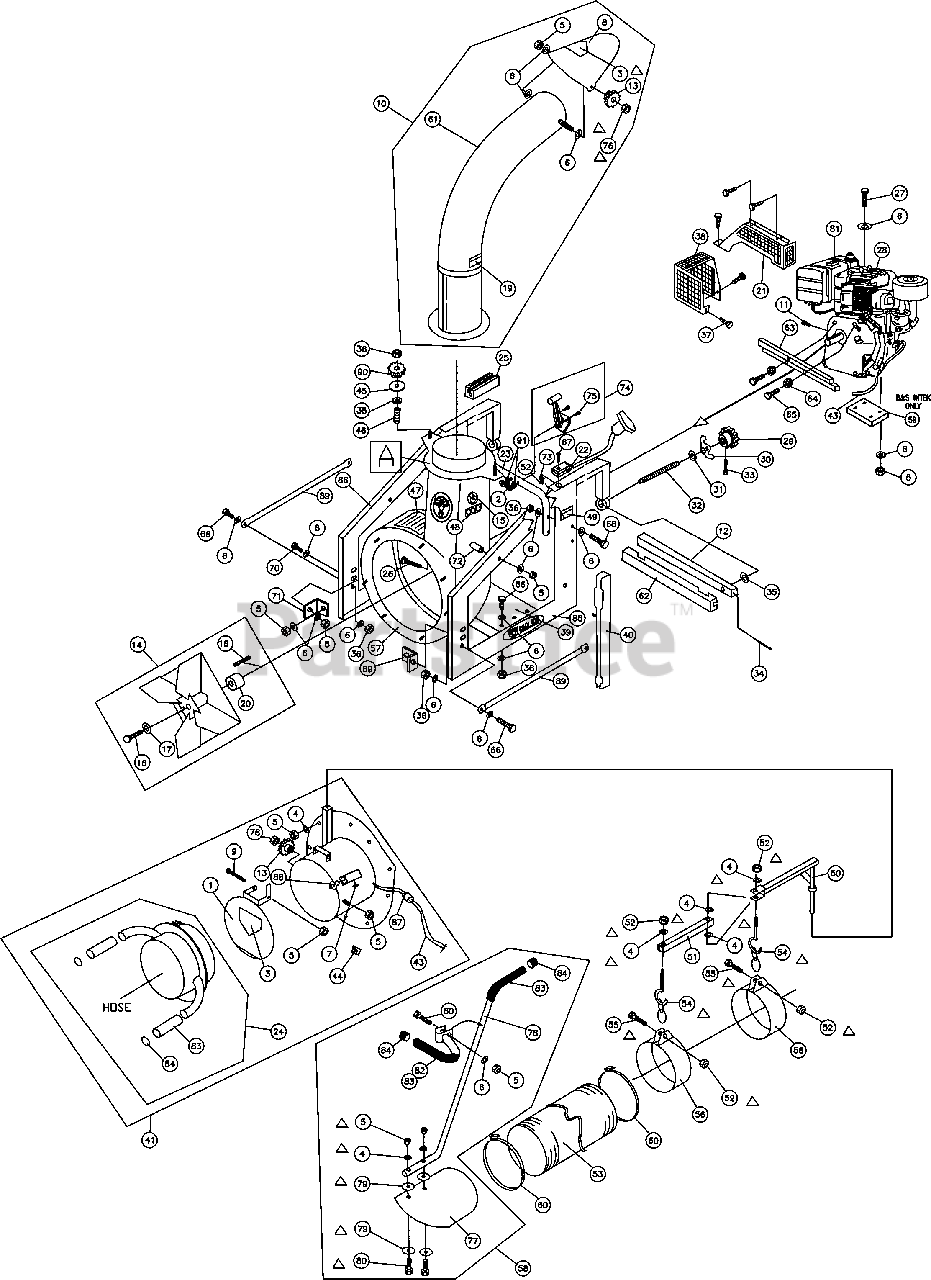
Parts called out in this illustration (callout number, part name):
1	FLAPPER 8" INTAKE W/ LABEL
2	NUT LOCK 10-24
3	LABEL DANGER KEEP HANDS AND FEET AWAY
4	WASHER 5/16 SAE (11/32 ID x 11/16 OD x 1/16)
5	NUT LOCK 5/16-18
6	WASHER 5/16 FLAT CUT (3/8 I.D. x 7/8 O.D. x 1/16)
7	PLUG 3/4"
8	DEFLECTOR EXHAUST 7"
9	CARRIAGE BOLT 5/16-18 x 3 1/2
10	ELBOW ASSY TR/HTR
11	SCREWCAP 5/16-18X.75
12	TUBE CLAMP
14	IMPELLER ASSY (INCLUDES 16(1),17(1),18(1), 20(1))
15	LABEL READ OWNER'S MANUAL
16	SCREW CAP 7/16 - 20 X 2 GR 5 [60 Ft. Lbs. (81.4 N.m)]
17	WASHER LOCK 7/16 TWISTED TOOTH
18	KEY SQ. 1/4 X 2 1/4
19	LABEL DANGER FLYING MATERIAL
20	SPACER IMPELLER
21	GUARD MANIFOLD
22	GUIDE STARTER ROPE (HALF)
23	TUBE REAR FRAME
24	COUPLER HOSE W/GRIP
25	PAD FRAME SHORT
26	CARRIAGE BOLT 5/16-18 x 4 1/2
27	SCREW CAP 5/16-18 x 2 1/2
28	ENGINE BRIGGS 11 HP INTEK I/C
30	NUT LOCK W.A.
31	WASHER 3/4, PLASTIC
32	STUD 3/4 -10 x 5 1/2
33	SCREW MACHINE #10-24 x 2
34	PIN COTTER 1/8 x 1"
35	WASHER 3/8 SAE
36	NUT LOCK 3/8-16
37	SCREW SHEET METAL 1/4 AB x 3/4
38	GUARD MUFFLER
39	BASE ENGINE
40	PAD FRAME LONG
41	PLATE FRONT 8" TR W/INTERLOCK (INCL. 1,2,3,5(2),7,13,43,44,49,59,83,84,87,88)
43	CABLE ASSY SWITCH SV
44	CLIP-CABLE LIFT
45	WASHER-1.5 OD X 0.531 ID
47	LABEL CAUTION
48	LABEL EAR,EYE,BREATHING
49	LABEL WARNING ENGINE OVERHEAT
50	BOOM-PIVOT W.A.
51	TUBE-SQUARE BOOM ARM
52	NUT LOCK 1/4-20
53	HOSE 8" x 12.5' TR
54	CHAIN-LOOP ASSY
55	SCREW CAP 1/4-20 x 1 3/4
56	BAND HOSE BOOM 8" TR
57	HOUSING ASSY W/LABELS (INCLUDES 5(2), 13(2), 45(2), 46(2), 47, 48)
58	NOZZLE ASSY 8" TR (INCL. 4(2), 5(3), 6, 23, 77, 79(4), 80(2), 82, 83, 84
59	SPACER ENGINE INTEK
60	CLAMP HOSE 8" TR
61	ELBOW EXHAUST WA
62	PAD FRAME CLAMP TUBE
63	SUPPORT PLATE ENGINE / SPACER ENG.
64	WASHER LOCK 5/16 EXT. TOOTH
65	SCREW CAP 3/8 - 16 X 1 1/2 ZP
66	SCREW CAP 3/8 - 16 x 1"
67	SCREW CAP 1/4-20 X 1 1/2
68	SCREW CAP 3/8 - 16 X 1 3/4 ZP
69	ANGLE BRKT R.H.
70	SCREW CAP 5/16-18 x 1"
71	ANGLE BRKT L.H.
73	WASHER FLAT CUT 1/4
74	CONTROL THROTTLE ASSY
75	SCREW MACHINE 10-24 x 1-1/2"
76	NUT LOCK 5/16-18 THIN HT.
77	NOZZLE FORMED STEEL 8"
78	HANDLE NOZZLE W / GRIP
79	WASHER FENDER 5/16
80	SCREW CAP 5 /16 - 18 X 1 1/2
81	LABEL DO NOT FILL WHEN ENGINE IS HOT
82	HANDLE LOOP NOZZLE
83	GRIP HANDLE
85	FRAME SIDE RIGHT WA TR/HTR
86	FRAME SIDE LEFT WA TR/HTR
87	STRAIN RELIEF
88	PLUNGER SWITCH
89	TUBE HANDLE LIFT
90	KNOB 3/8" SOLID HUB
91	PART NOT APPLICABLE ON THIS MODEL
